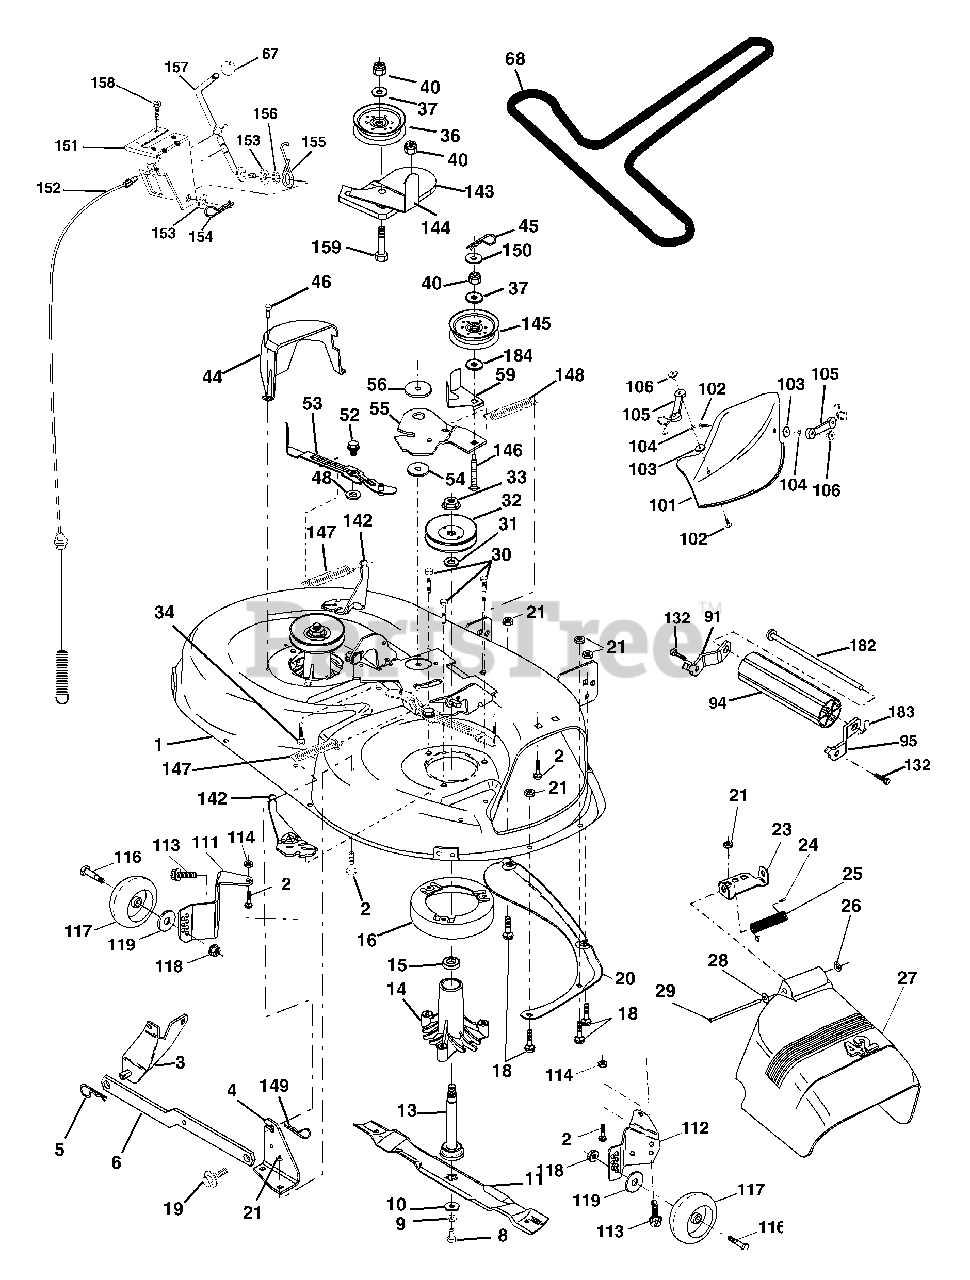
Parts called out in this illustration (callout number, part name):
1	Mower Deck Assembly, 42"
2	Bolt
3	Bracket Asm Fr. Sway Bar 3/42
4	Bracket Asm Deck 42" Sway Bar
5	Retainer Spring
6	Bar Sway Deck
8	Bolt 3/8-24 x 25 Gr. 8 patched
9	Washer, Lock
10	Washer, Hardened
11	Blade, Mulching 42"
11	Blade Mower 42" Hi-Lift
13	Shaft Assembly, Mandrel, Vented
14	Housing, Mandrel, Vented
15	Bearing, Ball, Mandrel
16	Stripper, Mandrel Deck
18	Bolt, Carriage 5/16-18 x 5/8
19	Bolt, Shoulder
20	Baffle, Vortex
21	Nut
23	Bracket, Deflector Mower 42"
24	Cap, Sleeve 80 x 112 Blk Mower
25	Spring, Torsion, Deflector 2 52
26	Nut, Push Phos & Oil
27	Shield, Deflector 42" Blk
28	Washer 11/32 x 5/8 x 16 Gauge
29	Rod, Hinge 42" 6 75 W/G
30	Screw Thdrol Washer Head
31	Washer, Spacer Mower Vented
32	Pulley, Mandrel
33	Nut, Toplock 9/16 Flange
34	Bolt
36	Pulley, Idler, Flat
37	Washer 13/32 x 13/16 x 16 Ga.
40	Nut
44	Guard, Mandrel, LH
45	Retainer
46	Screw, Thdrol 1/4-20 x 5/8 T
48	Washer, Hardened
49	Roller Assembly, Cam Follower
50	Bolt, Shoulder #10-24 Grade 5
51	Locknut
52	Bolt, Shoulder 5/16-18 Unc
53	Arm Assembly, Pad, Brake
54	Washer, Hardened
55	Arm, Idler
56	Spacer, Retainer
59	Guard TUV Idler
67	Knob
68	V-Belt, 42" Mower
91	Bracket Asm Noseroller LH
94	Roller Nose 38 & 42
95	Bracket Asm Noseroller RH
101	Mulcher Cover
102	Screw
103	Washer, Flat
104	Washer, Lock
105	Latch Assembly
106	Nut, Weld
111	Bracket, Gauge, Wheel LH
112	Bracket, Gauge, Wheel RH
113	Screw 3/8-16 x .625
114	Nut, Keps 5/16 - 18 Unc
115	Bolt, Carriage 5/16-18 x 5/8
116	Bolt, Shoulder
117	Wheel, Gauge
118	Nut Centerlock 3/8-16
119	Washer 3/8 x 7/8 x 14 Ga.
132	Screw 3/8-16 x .75
142	Arm Spring Brake Mower
143	Bracket Arm Idler 42"
144	Keeper Belt 42" Clutch Cable
145	Pulley Idler Flat
146	Bolt Carriage Idler
147	Spring Extension
148	Spring Return Idler
149	Retainer Spring Yellow
150	Washer 9/32 x 3/4 x 16 Ga.
151	Bracket Clutch Cable
152	Clutch Cable 42"
153	Washer Flat 3/8" Type B
154	Spring Retainer
155	Spring Retention LVR CLTCH CAB
156	Spacer Clutch Cable
157	Rod Clutch Cable 3/8"
158	Screw Hex Thd Cut 1/4-20 x 5/8
159	Bolt Rdhd Sqn 3/8-16 Unc x 1-3/4
182	Rod Nose Roller
183	Retainer Spring
184	Washer 13/32 x 7/8 x 10 Ga.
